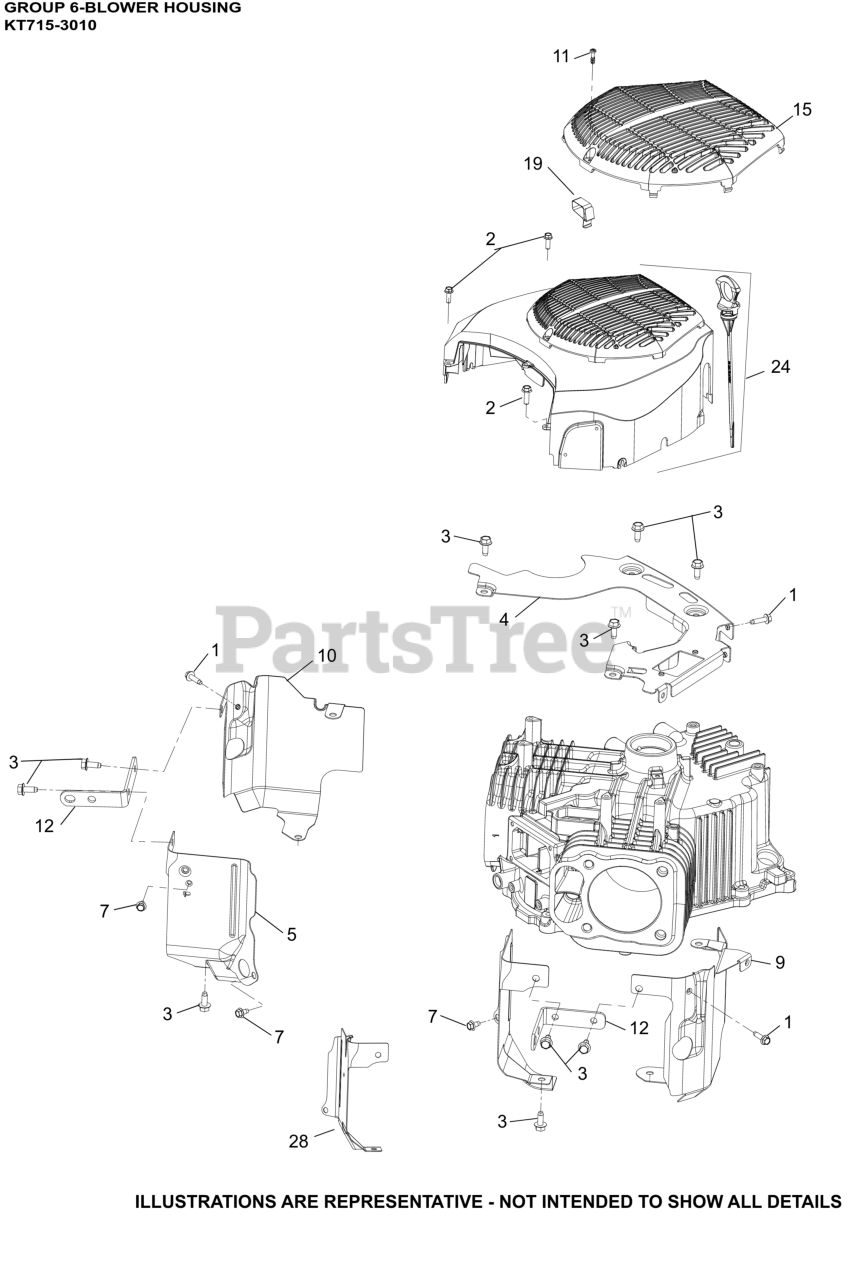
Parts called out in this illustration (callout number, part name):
1	SCREW, THD FRM-USE 25 086 473-S
2	SCREW, HI-LOW
3	SCREW, THREAD FORMING
4	PLATE, BACKING
5	BAFFLE, VALLEY #1
7	SCREW, THREAD FORMING
9	BAFFLE, LEFT BARREL
10	BAFFLE, RIGHT BARREL
11	SCREW, M5-2.42 (PT) THREAD
12	STRAP, LIFTING
15	GUARD, FIXED
19	CLIP, BLOWER HOUSING
24	KIT, BLOWER HOUSING
28	BAFFLE, VALLEY #2
